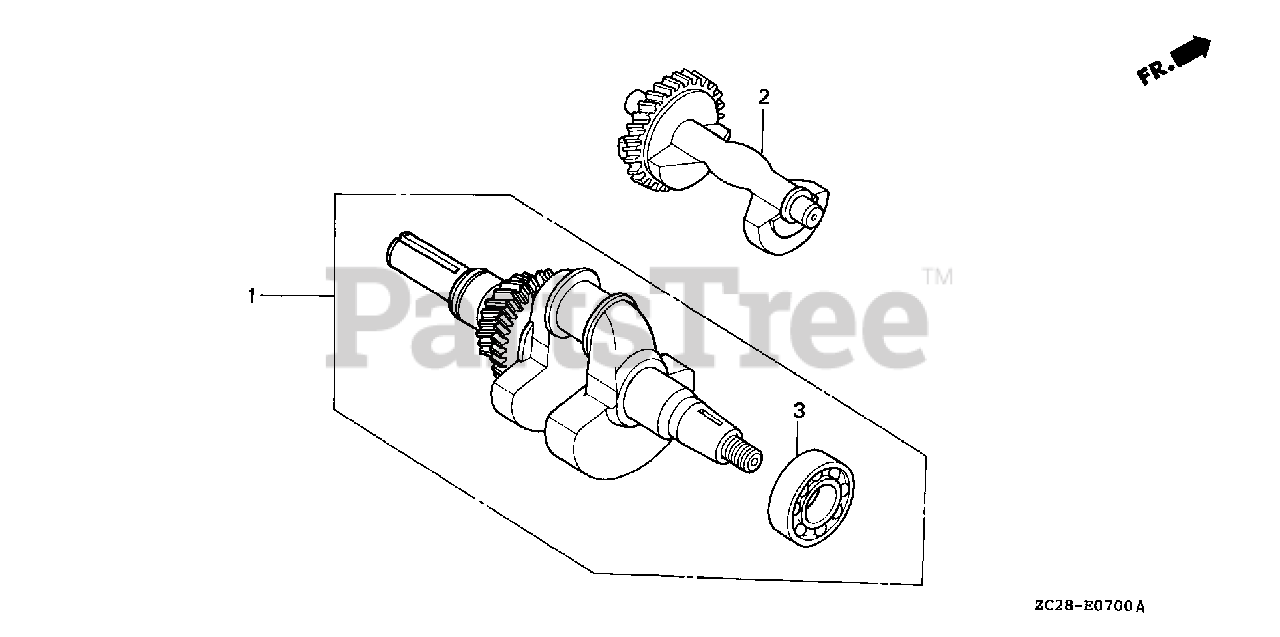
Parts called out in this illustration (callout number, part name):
1	CRANKSHAFT (E-TYPE)
1	CRANKSHAFT
2	WEIGHT, BALANCER
3	BEARING, RADIAL BALL (6207)
